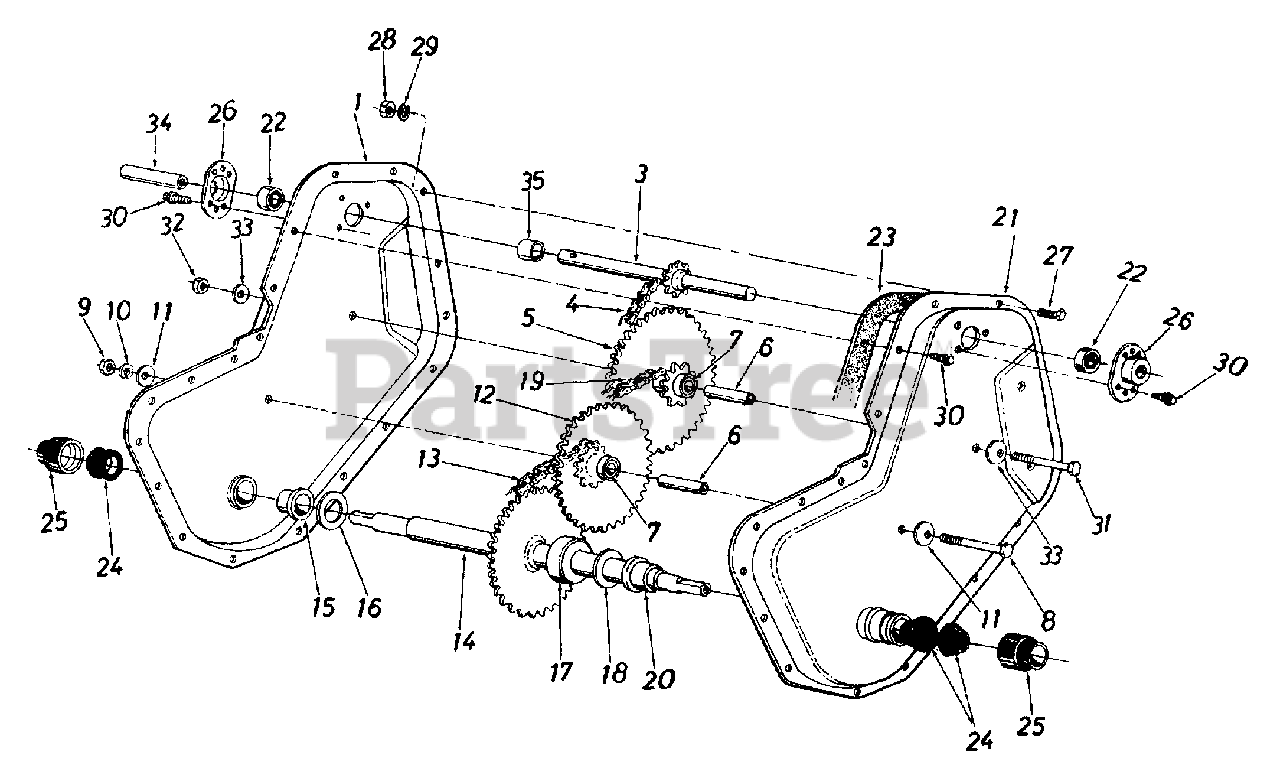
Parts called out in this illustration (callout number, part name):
3	Input Shaft Ass'y.
4	Chain #35 - 3/8" Pitch x 44 Links
5	Sprocket and Hub Ass'y.
6	Bearing Inner Axle
7	Sleeve Brg. 5/8" I.D. x 3/4" O.D. x 1.50
8	Hex Bolt 3/8-24 x 2.50" Lg.
9	Hex Ins. L-Nut 3/8-24 Thd.
10	L-Wash. 3/8" I.D.
11	Bell-Wash. .41" I.D. x 1.13" O.D. x .03
12	Sprocket & Hub Ass'y. 9T-22T
13	#420 Chain 1/2 Pitch x 28 Links Endless
14	Wheel Shaft Ass'y.
15	Flange Bearing
16	Fl-Wash. .88" I.D. x 1.5" O.D. x .03
17	Spacer 7/8" I.D. x 1 3/4" O.D. x .68" Lg.
18	Fl-Wash. .88" I.D. x 1.50" O.D. x .03
19	#420 Chain 1/2" Pitch x 30 Links Endless
20	Flange Bearing
23	Gasket
25	Dust Cup
26	Bearing Housing
27	Hex Bolt 1/4-28 x 5/8" Lg.
28	Hex Nut 1/4-28 Thd.
29	L-Wash. 1/4" I.D.
30	Hex Wash. S-Tap Scr. 1/4-20 x .50" Lg.
31	Hex Bolt 5/16-18 x 2.5" Lg.
32	Hex Cent. L-Nut 5/16-18 Thd.
33	Fl-Wash. 5/16" I.D.
34	Spacer .64" I.D. x 1.76" Lg.
35	Spacer .64" I.D. x .45" Lg.
